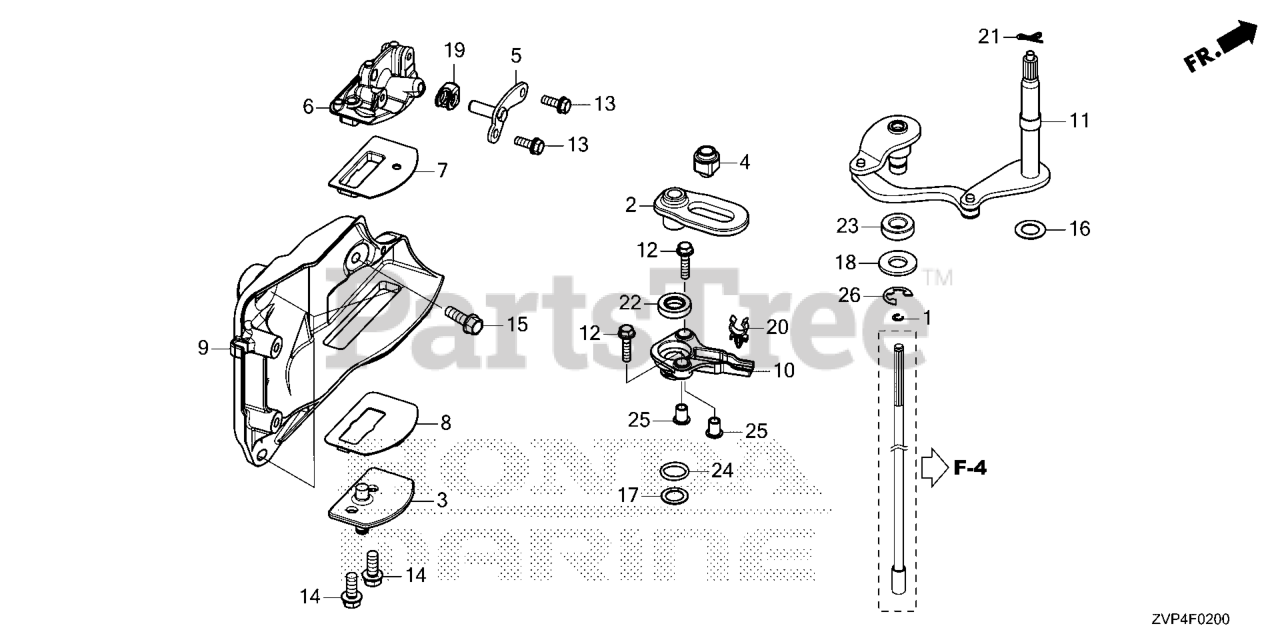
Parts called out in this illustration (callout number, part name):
1	RING, STOPPER
2	ARM, SHIFT
3	PIN, SHIFT LINK
4	ROLLER, SHIFT
6	PIVOT, SHIFT
7	SLIDER A, SHIFT
8	SLIDER B, SHIFT
9	GUIDE, SHIFT LINK
10	HOLDER, SEAL
11	SHAFT COMP, SHIFT
12	BOLT, FLANGE (6X25)
13	BOLT, FLANGE (6X16)
14	BOLT, FLANGE (8X20)
15	BOLT, FLANGE (8X25)
16	WASHER B, THRUST (14MM)
17	WASHER (14MM)
19	RUBBER, BUMPER
20	CLAMP, HOSE (NOT AVAILABLE)
21	PIN, SNAP (6MM)
22	OIL SEAL (14X26X6)
23	SEAL, WATER (14X26X8)
24	O-RING (18X2.4)
25	COLLAR, DISTANCE (6.5X9X11.5)
26	E-RING (12MM)
